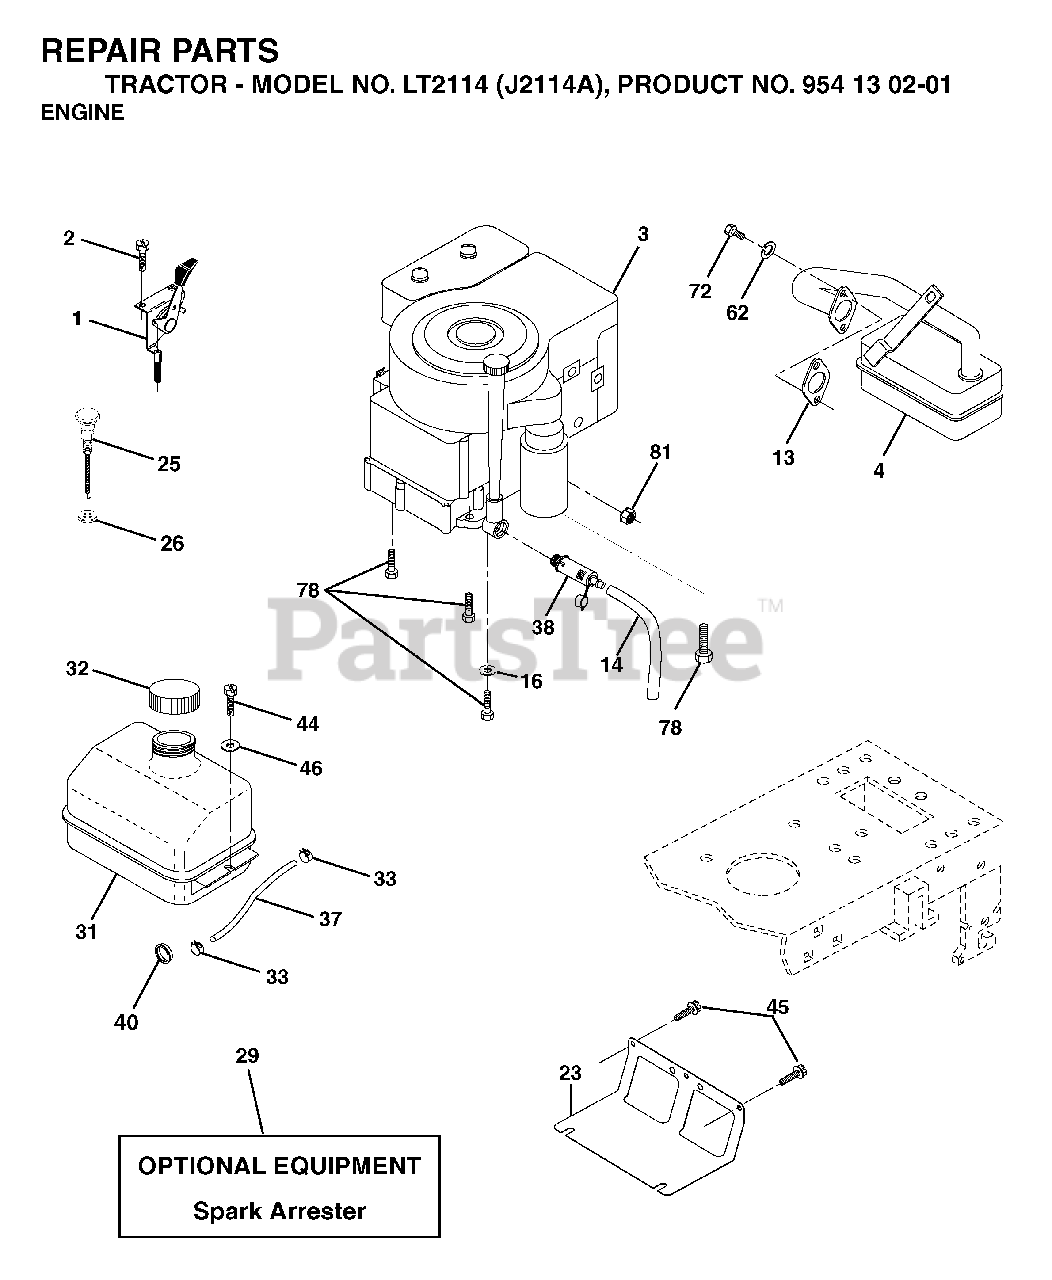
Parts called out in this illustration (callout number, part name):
1	CONTROL TH/CH FLAG
2	SCREW
13	REPL BY 532 27 22-93
14	TUBE, DRAIN OIL ASM.
16	LOCKWASHER
23	SHEILD.BROWNING.DBR.GUARD
26	NUT KEPS 3/8 - 24 UNF
29	ARRESTER SPARK (OPTIONAL)
32	FUEL CAP
33	HOSE CLAMP
37	LINE.FUEL.20
38	PLUG DRAIN OIL EASY
40	GROMMET T
44	SCREW HEXWSHR 1/4-20X3/4
45	SCREW, 3/8-16X3/4
62	LOCKWASHER
72	SCREW
78	SCREW.3/8-16
81	NUT
